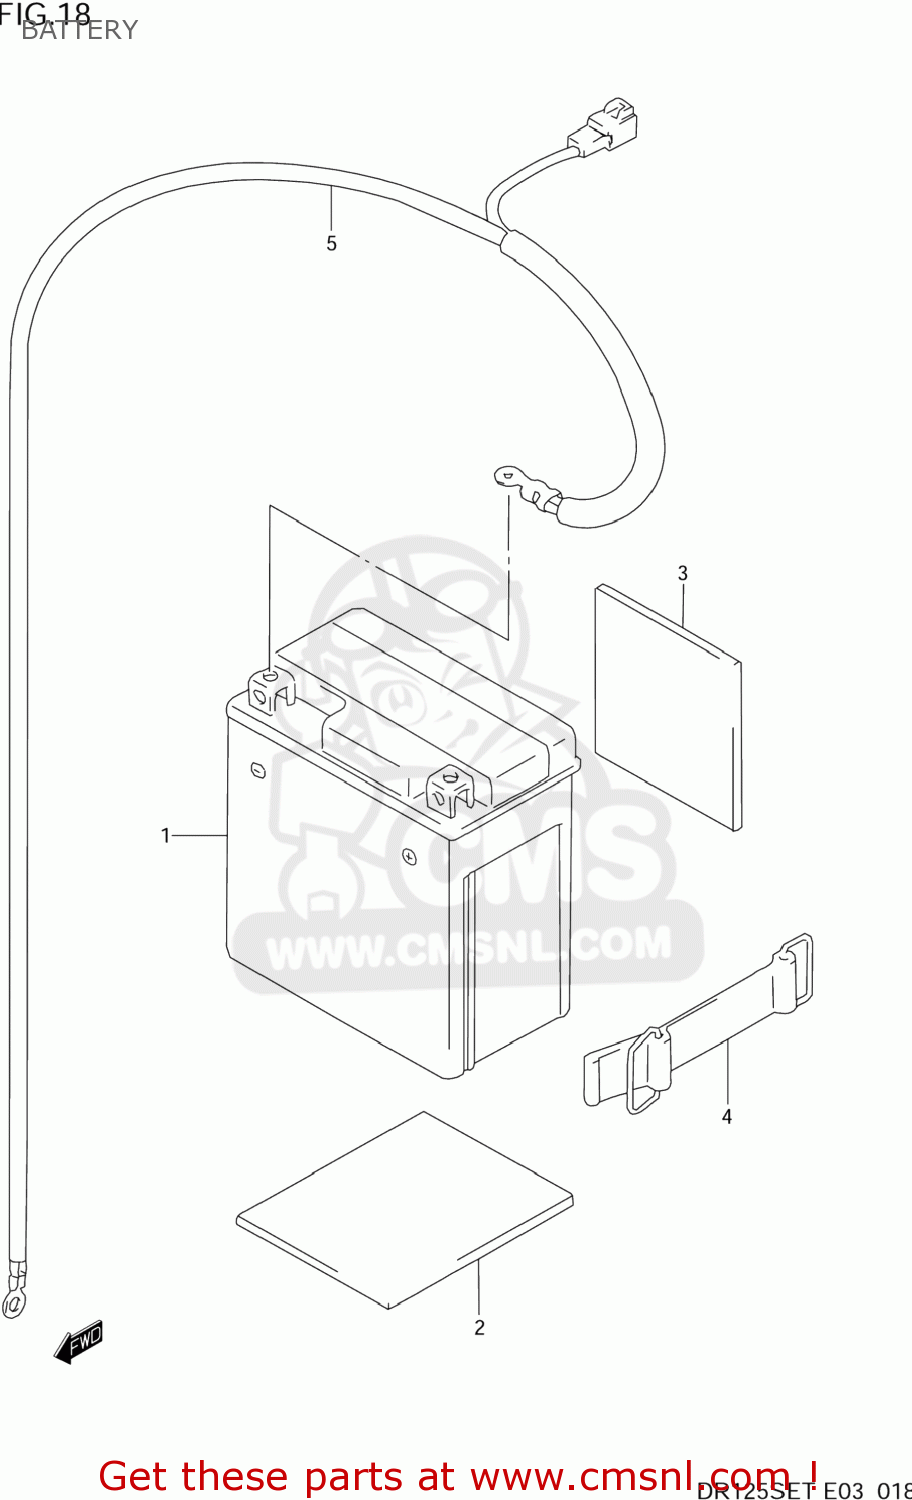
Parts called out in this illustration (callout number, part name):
1	BATTERY ASSEMBLY (12V) YTX
2	PROTECTOR(170X95X3.0)
3	PROTECTOR(170X95X3.0)
4	BAND
5	WIRE,BATTERY MINUS
